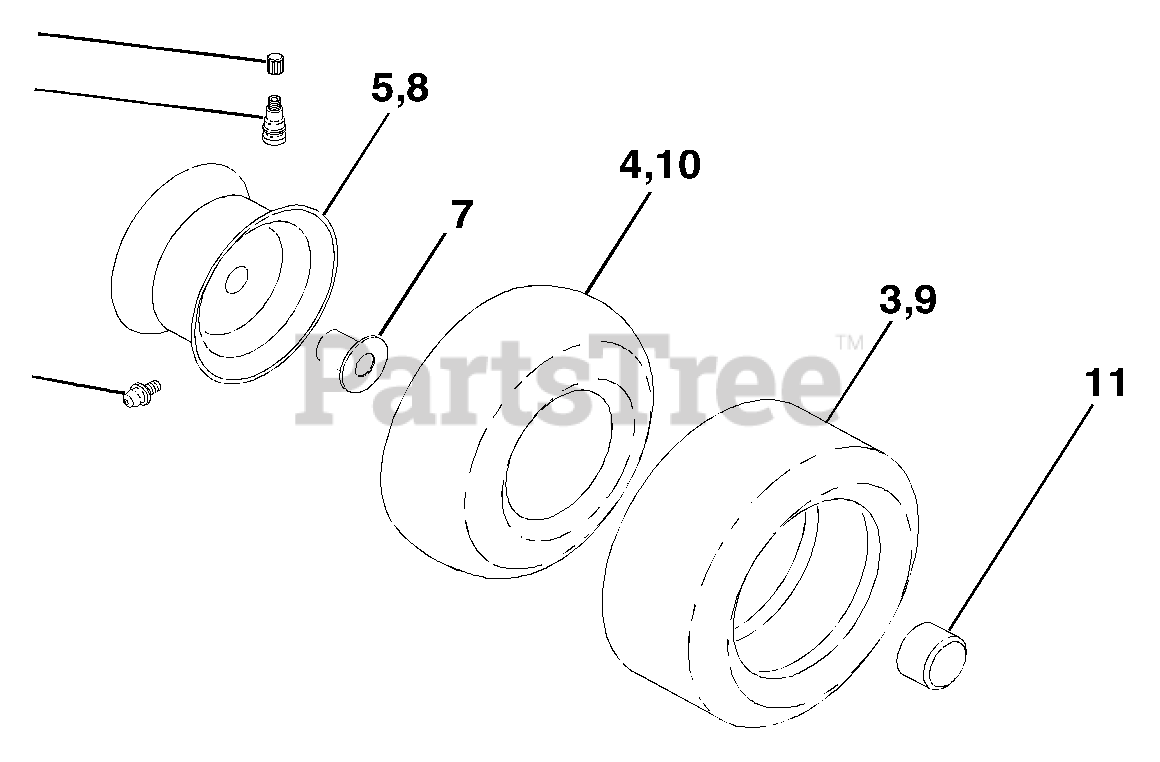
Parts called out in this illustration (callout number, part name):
1	Cap Valve Tire
2	Stem Valve
3	Tire F Ts 15 X 6 0 - 6 Service
4	Tube Front
5	Rim Asm 6" front White Service
6	Fitting Grease
7	Bearing Flange
8	Rim Asm 8" rear White Service
9	Tire R Ts 18x8.5-8 C Service
10	Tube Rear
11	Cap Axle Blk 1 50 X 1 00
